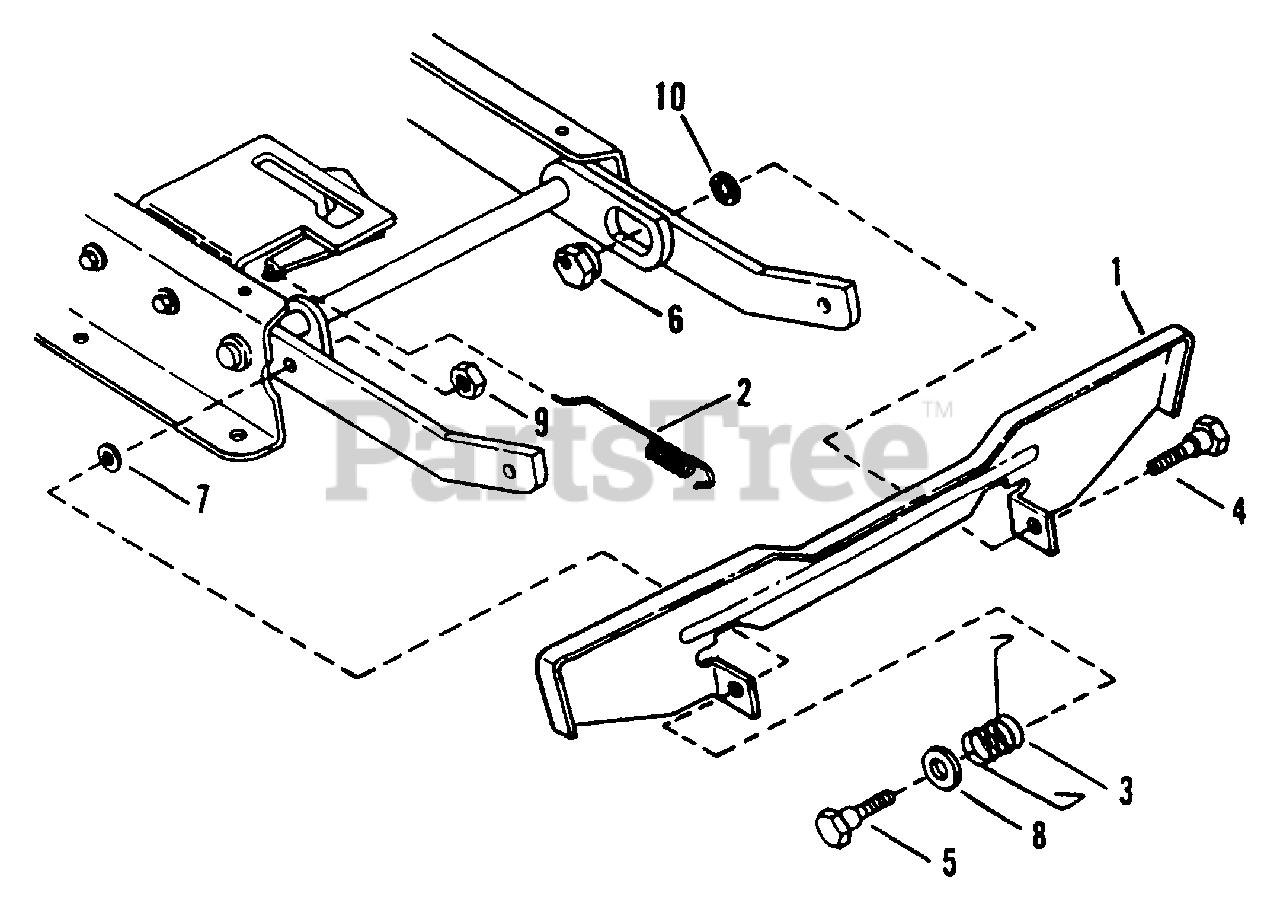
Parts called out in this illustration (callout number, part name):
1	PEDAL, Blade Stop Control
2	SPRING, Latching
3	SPRING, Pedal
4	BOLT, 3/8-24 x 3/4" Shoulder
5	BOLT, 3/8-24 x 9/16" Shoulder
6	ECCENTRIC, Leveling
7	WASHER, 3/8" Flat
8	WASHER, 1/2 Flat
9	NUT, 3/8-24 Hex Lock
10	WASHER, 3/8 Internal Tooth Lock
